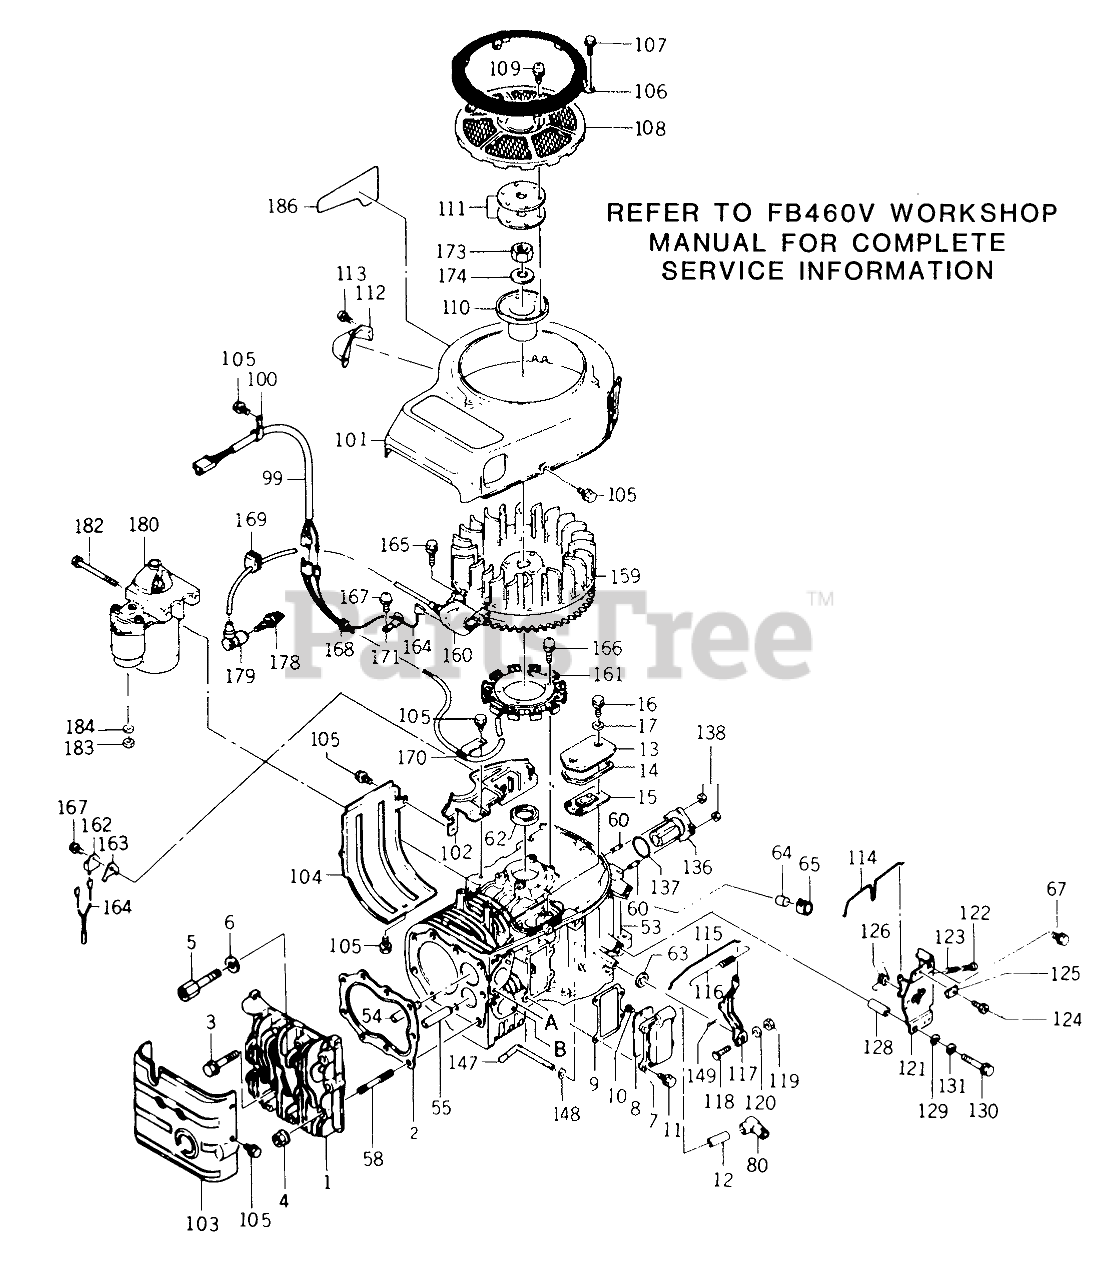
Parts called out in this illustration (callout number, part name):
1	Head-Cylinder
2	Gasket
3	Bolt
6	Washer
7	Cover-Valve Chamber
11	Bolt-Flanged (6X16)
16	Bolt
53	Crankcase Complete (includes items 54 & 55)
54	Guide-Intake Valve
55	Guide-Exhaust Valve
63	SEAL-OIL (VC6X10X2.6)
67	BOLT-FLANGED (6X10)
100	Clamp
101	Fan Housing
102	Fan Housing
105	BOLT-FLANGED (6X10)
107	Bolt 5x8
109	Screw 6x16
111	Shim T-1.20
113	Screw 4x8
114	LINK-Choke
115	Link
117	Arm ASM
118	Bolt (6X28)
119	Nut 6 mm
120	Washer
121	Control Panel Assy (includes items 122, 123, 124, 125 & 126)
122	Screw 4x25
124	Bolt
130	Bolt 6x50
131	Spring Washer
136	Shaft
138	Nut
147	Arm-Pivot
148	Washer
149	Pin-Snap (1.2 X 21.2)
159	Flywheel Complete
160	Coil
161	Charging Coil
162	Igniter
164	Lead Wire
165	Bolt 5x25
166	Screw 6x20
167	Screw 4x8
171	Clamp
178	Spark Plug
180	Electric Starter Assy-see section 9-7 for parts breakdown
183	Nut 8 mm
184	WASHER 5/16 SAE
